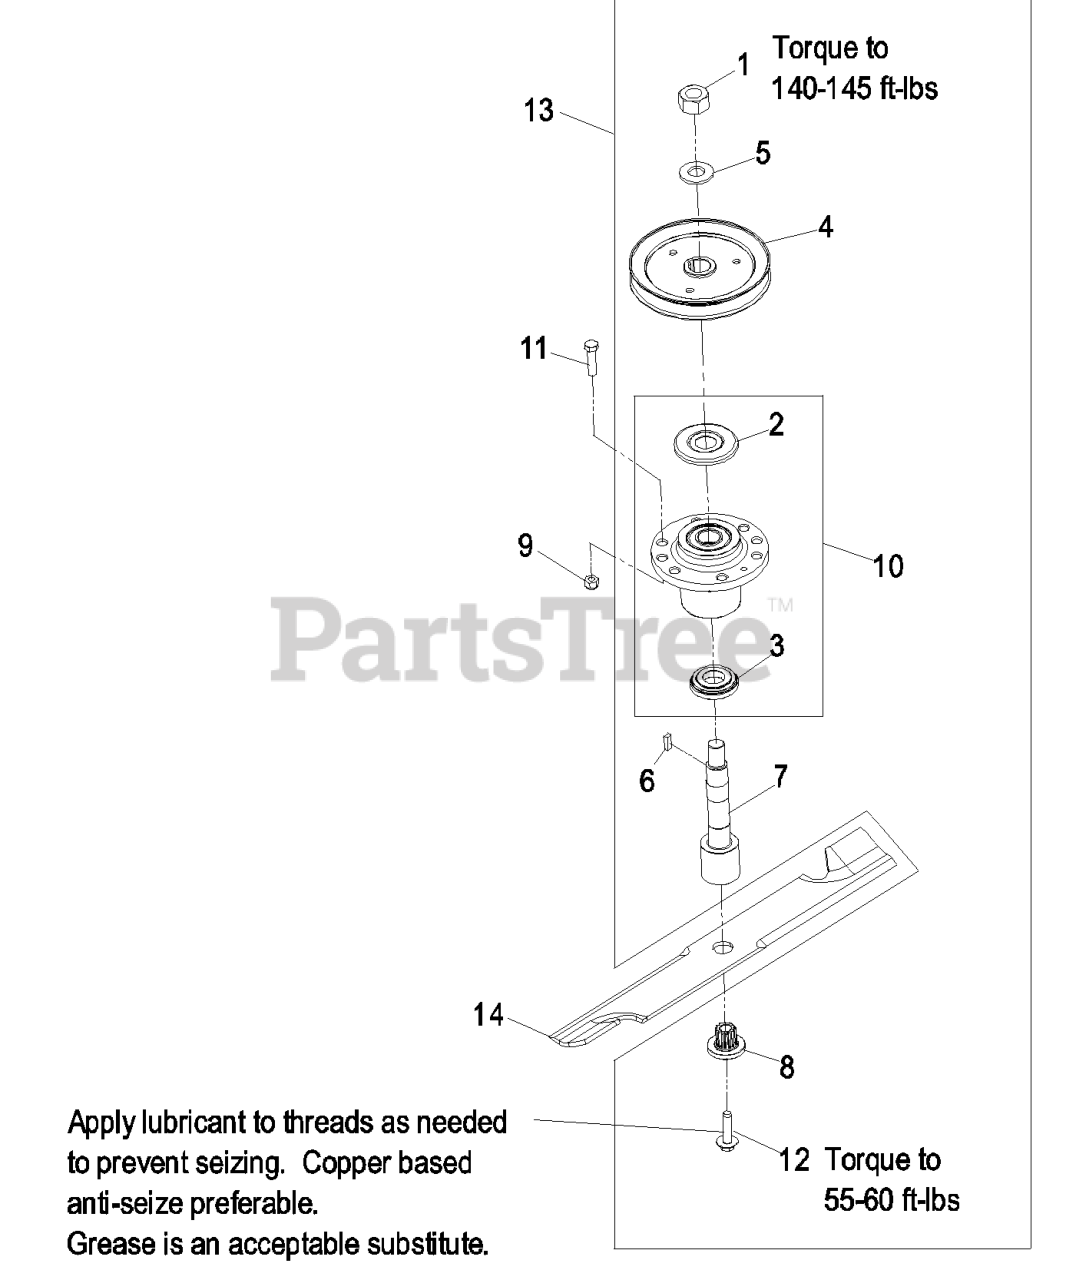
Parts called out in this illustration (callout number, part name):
1	NUT-HH
2	GUARD-BEARING, TOP
3	SPACER-GUARD, BOTTOM
4	SHEAVE,BLADE DRIVE 6.30
7	KIT, SPLINED SPINDLE 103-
8	BUSHING,SPLINED
9	NUT-LOCK, NI
10	KIT, CUTTER HOUSING
11	SCREW-HH
13	ASM, CUTTER HSG COMPLETE
